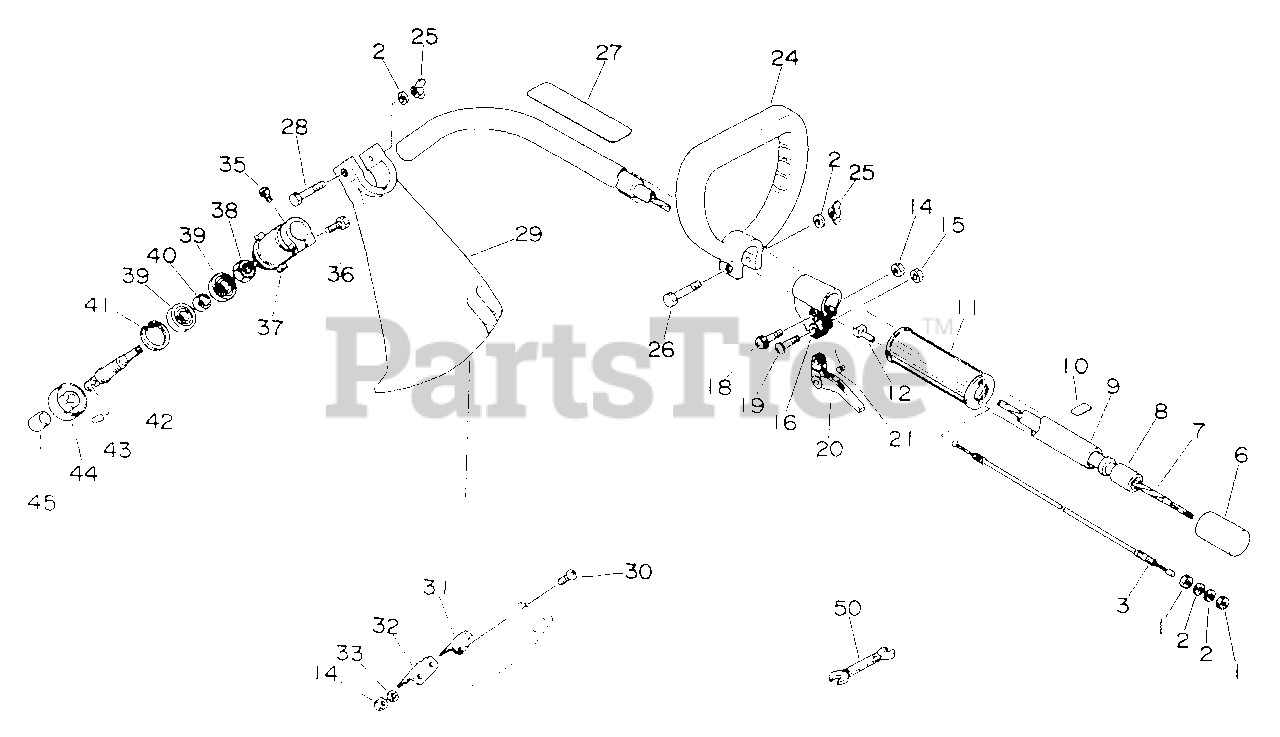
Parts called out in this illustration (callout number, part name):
2	WASHER - 6
3	CABLE, THROTTLE
6	CAP
7	DRIVESHAFT - FLEXIBLE
8	BUSHING
9	PIPE, MAIN
10	LABEL - ALIGNMENT
11	GRIP, HANDLE
12	GUIDE, CABLE
15	LOCKNUT - 5
16	BRACKET, TRIGGER
18	SCREW - 5X28
19	SCREW - 5X30
20	TRIGGER, THROTTLE
21	SPRING, TRIGGER
24	HANDLE ASSY
25	WINGNUT - 6
26	BOLT - 6X40
27	LABEL - CAUTION
28	BOLT - 6X50
29	SHIELD, DEBRIS - PLASTIC
30	SCREW - 5X14
31	KNIFE, TRIMMER LINE
33	LOCKWASHER - 5
35	SCREW - 4X10
36	BOLT - 5X25
37	CASE, GEAR
38	NUT - 12 -- LEFT HAND
39	BEARING, BALL - 6001 DDU
41	RING, RETAINING - 28
42	GEAR - SHAFT
43	PIN - 3X6
44	ADAPTOR, BLADE - UPPER
45	CAP, DRIVESHAFT
50	SPANNER - 8X10mm
